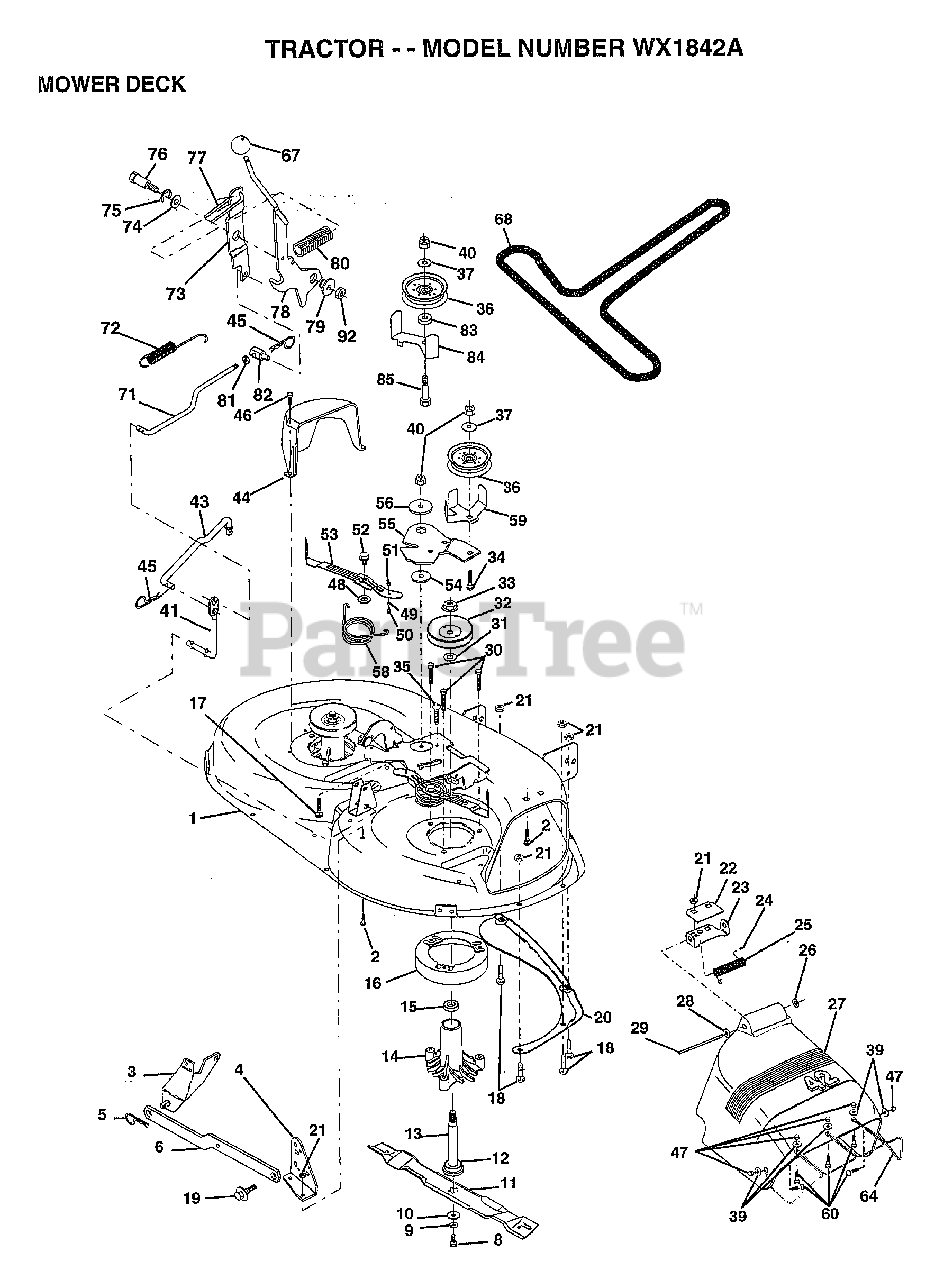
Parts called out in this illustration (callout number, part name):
1	DECK.WELD.42.
2	BOLT
3	BRKT ASM SWAY BAR
4	BRKT DECK SW BAR
8	BLADE BOLT
10	WASHER.HARD.BLADE
11	"BLADE.42"" HIPERF"
12	BEARING.BALL
14	HSG ASM MANDREL
15	BEARING
16	STRIPPER RND MWR
17	BOLT RDHD 3/8-16
18	BOLT
19	BOLT SHD 5/16-18
22	STIFFENER BRKT
23	DEFLECTOR BRKT
24	CAP-SLEEVE LT
26	NUT PUSH M
27	DEFLECTOR.CLIP.TU
28	WASHER
29	HINGE ROD
31	WASHER
34	BOLT
35	XMAS TREE FASTNER
36	FLAT IDLER PULLEY
37	WASHER
41	PIVOT ROD
43	ROD CLUTCH W/NIBS
44	GUARD MAND LH BLK
45	RETAINER M
46	SCREW.1/4-20X5/8
47	ACORN NUT RB
48	HARD SMALL WASHER
50	SHOULDER BOLT
51	LOCKNUT
52	BOLT.SHLD.5/16-18
53	BRAKE PAD ARM ASM
54	HARDENED WASHER
56	SPACER RETAINER
58	SPRING TORSN BRAK
59	GUARD IDLER TUV
60	SCREW
64	GUARD.FOOTREST.42
67	KNOB T(3/8 HOLE)
68	BELT.V.T-PATH
71	ROD CLUTCH 38/42
72	RETURN SPRING
73	CLUTCH ARM SECOND
74	WASHER
75	RING
76	SHOULDER BOLT
77	SPRING KEEPER
79	BUSHING
81	NUT
82	TRUNION ADJ
83	WASHER
85	BOLT RDHD 3/8-16
92	NUT
